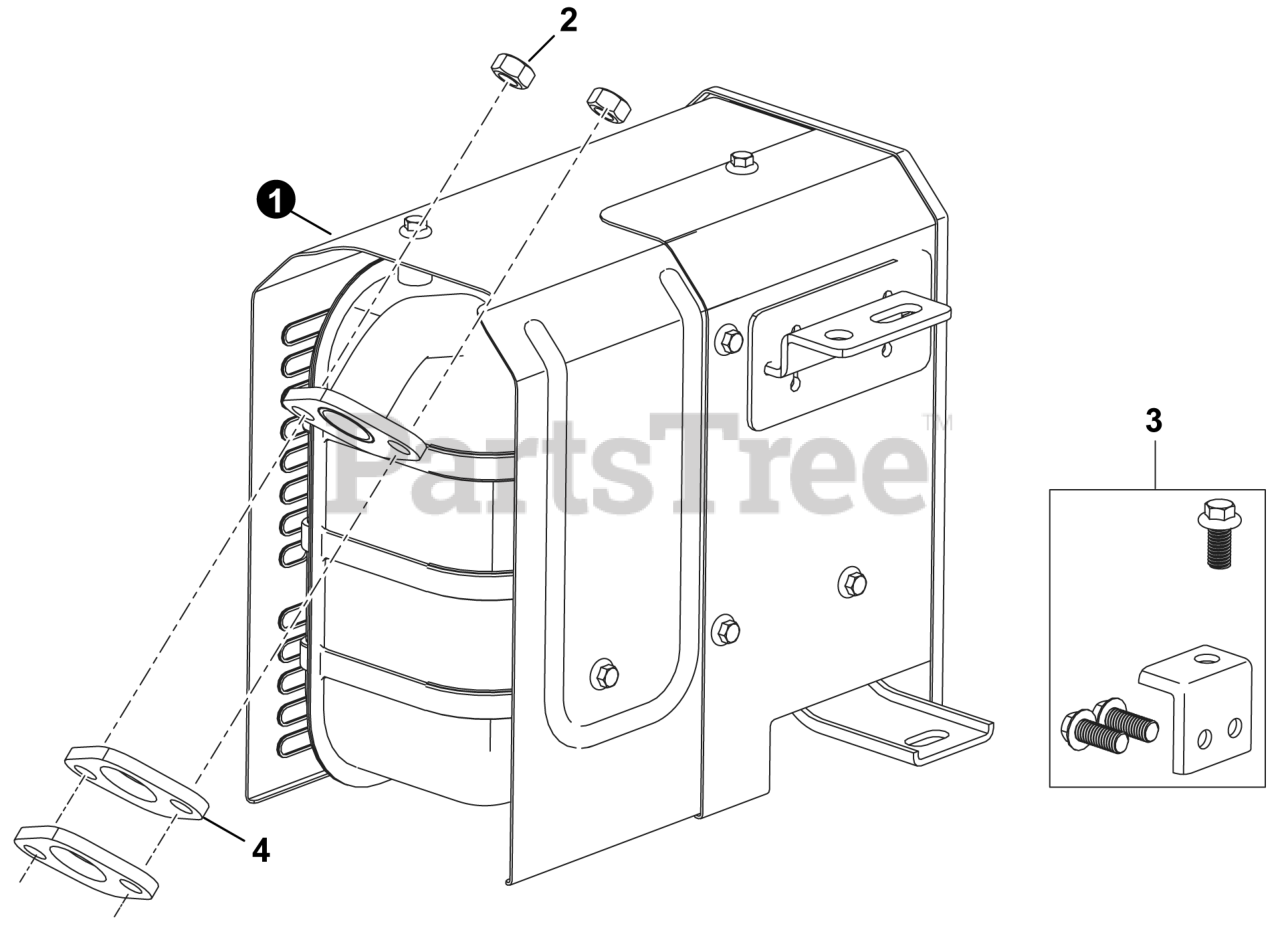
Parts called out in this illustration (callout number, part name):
1	MUFFLER ASSY.
3	BRACKET,MUFFLER
4	GASKET, EXHAUST OUTLET
